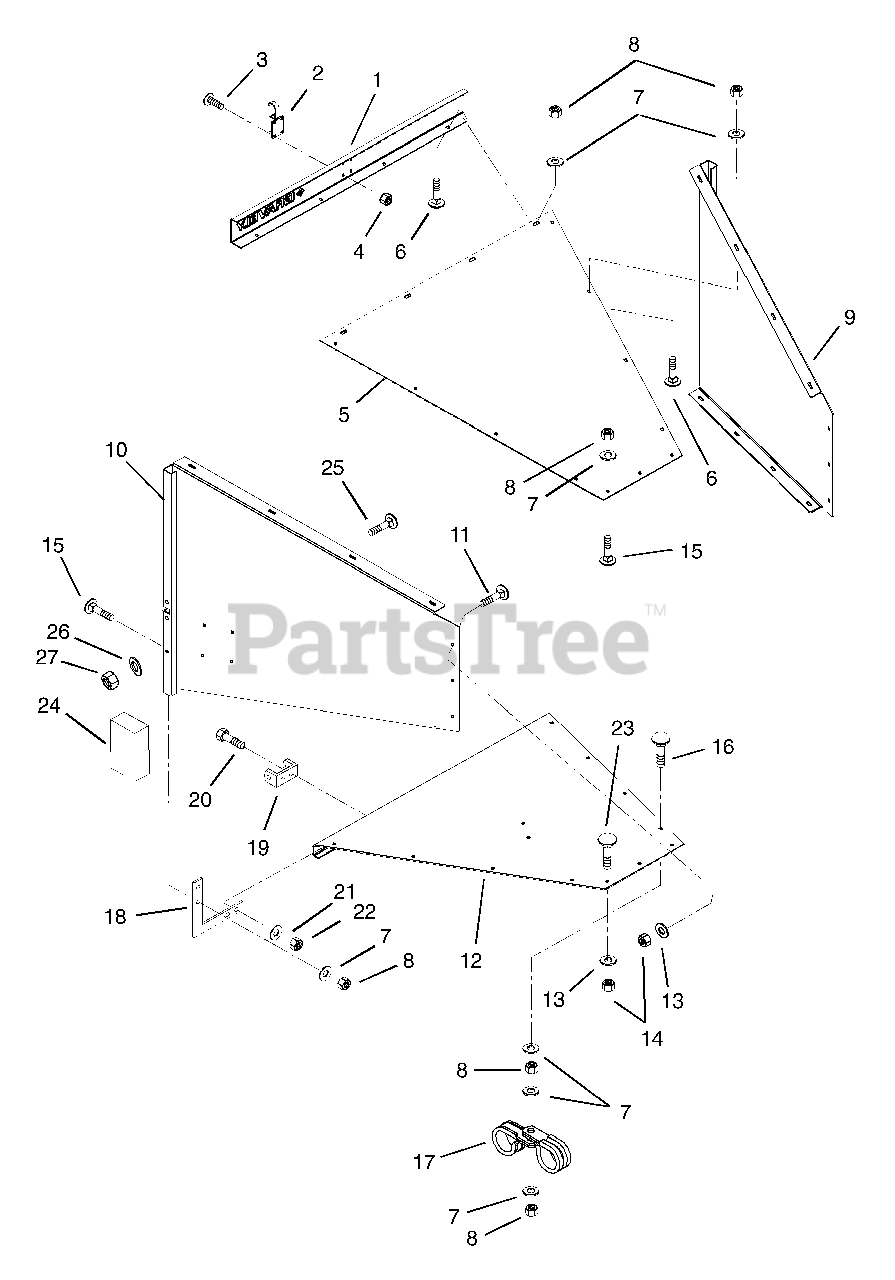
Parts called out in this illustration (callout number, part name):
1	Hopper Safety Tab
3	Screw-Machine 10-24 x .50
4	Nut-Locking-Nylon 10-24 w/Insert
5	Hopper Top
6	Bolt-Round Head Square Neck .31-18 x .75
7	Washer-Flat-Steel .38 x .875 x .083
8	Nut-Locking .375-16
9	Hopper-Left Hand Side
10	Hopper-Right Hand Side
11	Bolt-Round Head Square Neck .50-13 x 1.25
12	Hopper Bottom
13	Washer-Flat-Steel .563 x 1.38 x .109
14	Nut-Locking-Center .50-13
15	Bolt-Round Head Square Neck .38-18 x 1.00
16	Bolt-Round Head Square Neck .38-18 x 1.25
17	Clamp-Steel 1.0
18	Reinforcement-Hopper Corner
19	Hinge-Apron
20	Bolt-Hex .38-16 x 1.25 Grade 5
21	Washer-Flat-Steel .438 x 1.00 x .083
22	Nut-Locking-Center .38-16
23	Bolt-Round Head Square Neck .50-13 x 1.00
24	Box-Literature
25	Bolt-Round-Head-Square-Neck .25-20 x .50 Grade 5
26	Washer-Flat-Steel .312 x .734 x .065
27	Nut-Locking Center .25-20
